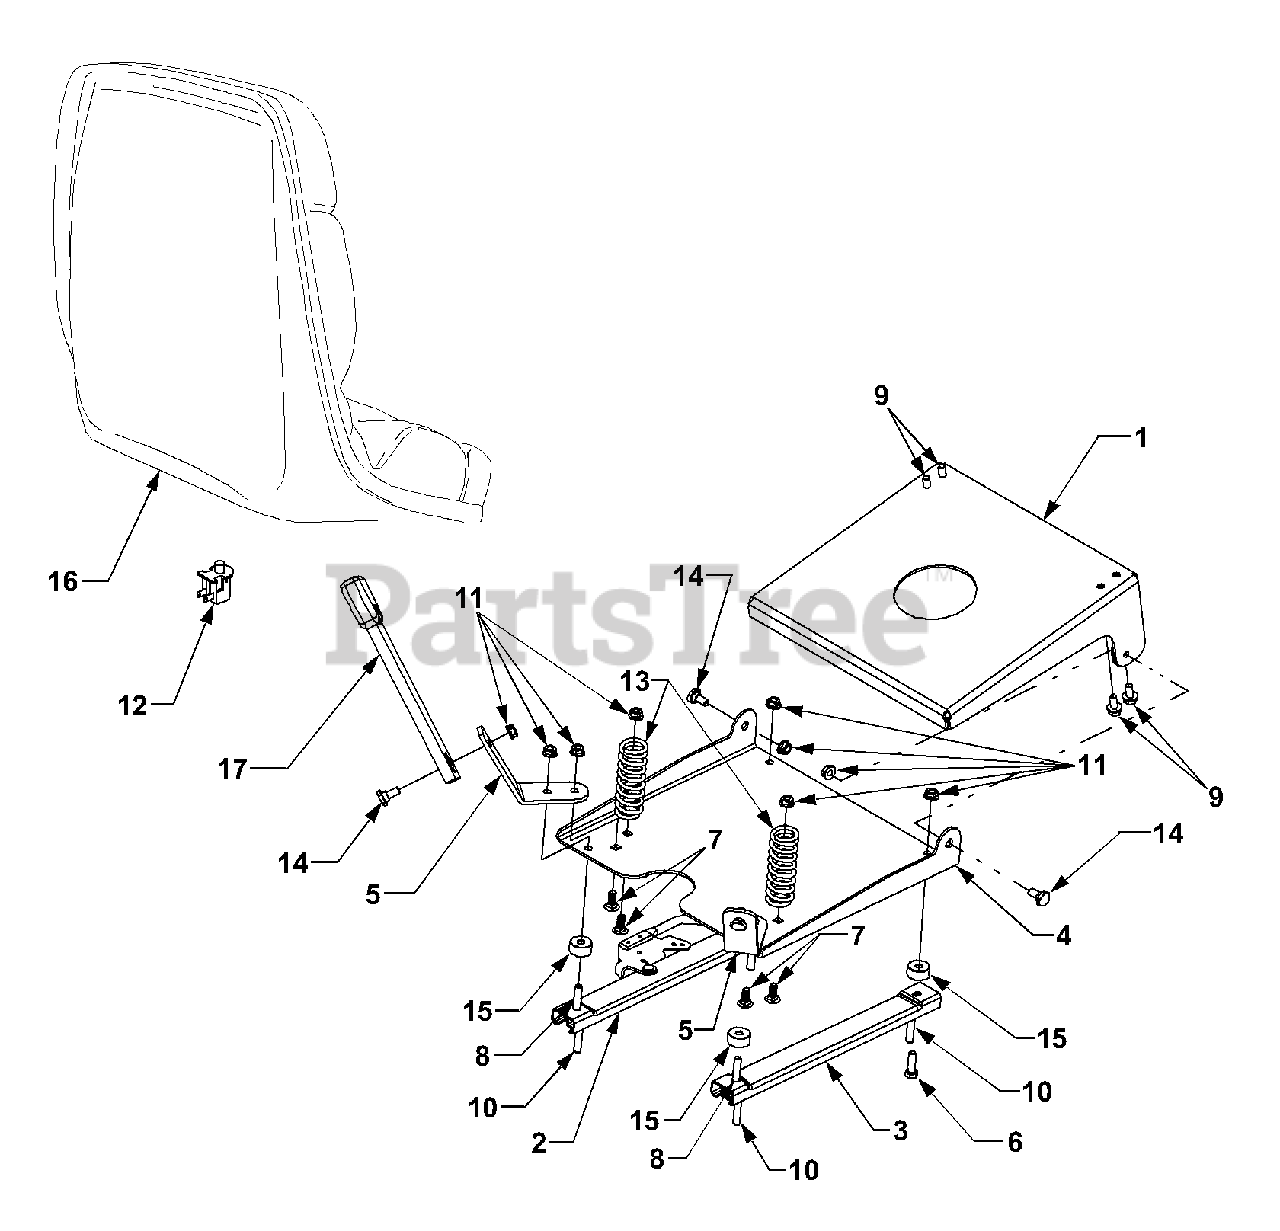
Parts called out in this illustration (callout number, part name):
1	Support, Seat - Upper
2	Track Ass'y., Seat w/Latch
3	Track Ass'y., Seat w/o Latch
4	Tray, Lower Seat
5	Bracket, Seat Belt
6	Screw, Hex Cap, 5/16-18 x 1.0 GR5
7	Screw, Carriage, 5/16-18 x .75
8	Screw, Hex Cap, 5/16-18 x 1.25 GR5
9	Screw, Hex Flange, 5/16-18 x .625 GR5
10	Screw, Socket Hd Cap, 5/16-18 x 1.5
11	Nut, Hex Flange Lock, 5/16-18
12	Switch, Snap Mount (N.O.)
13	Spring, Compression, 1.28 x 3.5
14	Screw, Shoulder, .435 x .178-5/16-18
15	Spacer, .315 x .750 x .375
16	Seat, High Back
17	Belt Assembly, Seat
